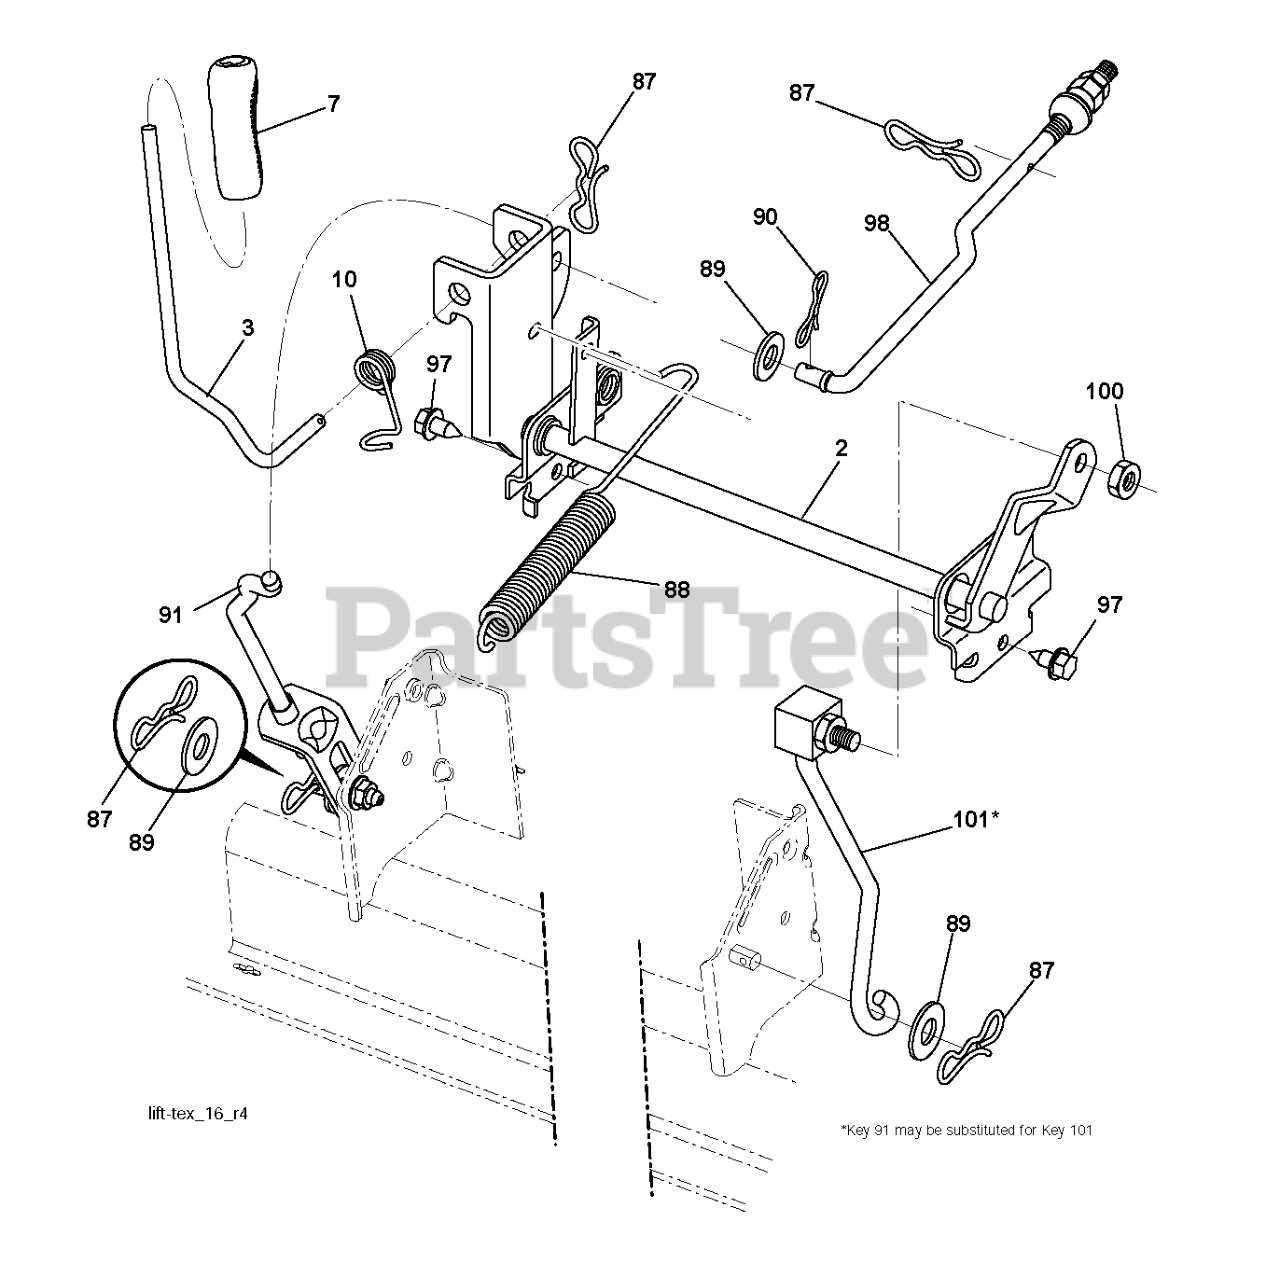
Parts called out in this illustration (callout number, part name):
2	SHAFT.ASM.LIFT.CROSS.H
3	LEVER.LIFT.HANDLE.LT
7	GRIP.HANDLE.LIFT.PVC.BLACK
10	SPRING.TORSION.LIFT.HANDLE
87	PIN.COTTER.7/16.BOW TI.
88	SPRING.LIFT.ASSIST
89	WASHER.CLEAR.ZINC
90	PIN.COTTER.5/16.BOW TI
91	LINK.ASM.LIFT.REAR
97	SCREW, 3/8-16X3/4
98	LINK.ASM.SUSP.FRONT.MW
100	LOCKNUT
101	LINK.ASM.LIFT.FIXE.38/42/46"
